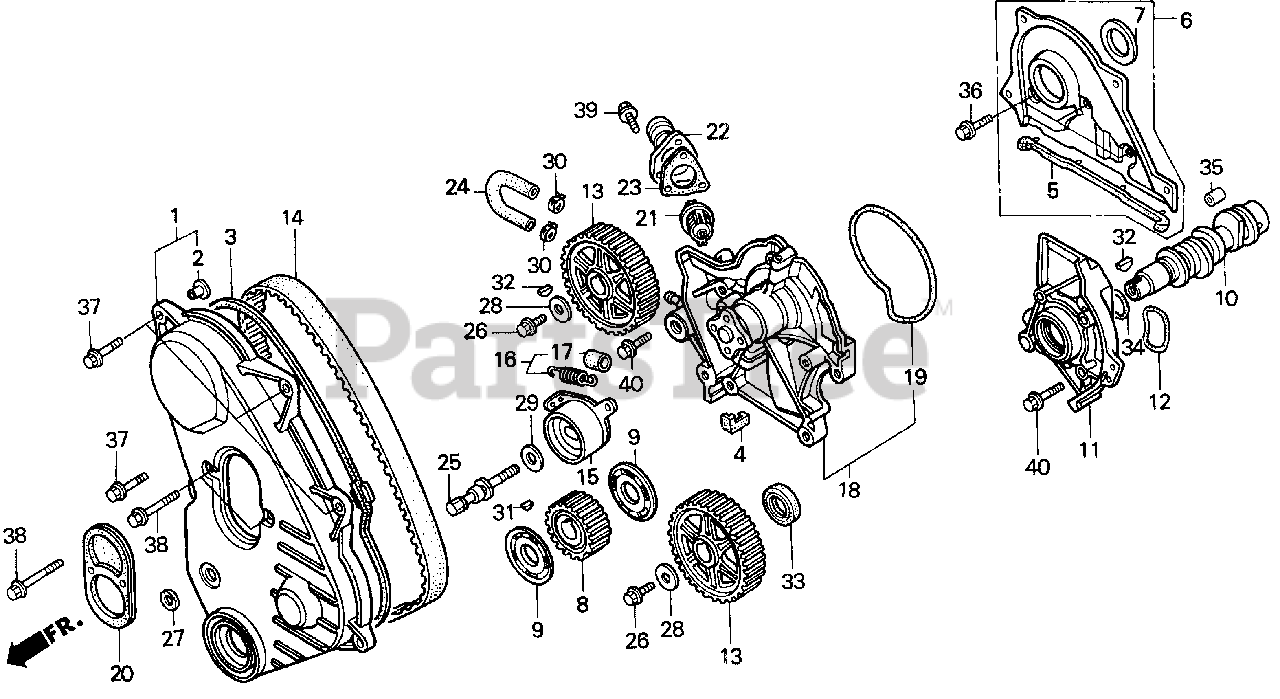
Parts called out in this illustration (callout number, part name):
1	COVER A, TIMING BELT
2	COLLAR, TIMING BELT COVER (LOWER)
3	RUBBER A, SEAL
4	RUBBER, R. BACK SEAL
5	RUBBER C, SEAL
6	COVER, RR. TIMING BELT
7	RUBBER, RR. COVER SEAL
8	PULLEY, TIMING BELT DRIVE
9	PLATE, TIMING BELT GUIDE
10	CAMSHAFT, FUEL
11	COVER, FUEL CAM
12	GASKET, FUEL CAM COVER
13	PULLEY, TIMING BELT DRIVEN
14	BELT, TIMING
15	TENSIONER, TIMING BELT
16	SPRING, TIMING BELT ADJUSTING
17	BOOT, SPRING
18	WATER PUMP
19	O-RING, WATER PUMP
20	RUBBER, WATER PUMP SEAL
21	THERMOSTAT
22	COVER, THERMOSTAT
23	GASKET, THERMOSTAT COVER (NON-ASBESTOS)
24	HOSE, WATER BYPASS
25	BOLT, TIMING BELT ADJUSTER
26	BOLT, FLANGE (8X22)
26	BOLT-WASHER (8X22)
27	RUBBER, TIMING BELT ADJUSTER
28	WASHER, SPECIAL (28X8.5X4.0)
29	WASHER (10.3X25)
30	CLAMP, CANISTER HOSE
31	KEY (4.5X11.0)
32	KEY (25.4X13)
33	OIL SEAL (29X45X8)
34	O-RING (64X2.3)
35	PIN, DOWEL (10X12)
36	BOLT, FLANGE (6X12)
37	BOLT, FLANGE (6X16)
38	BOLT, FLANGE (6X20)
39	BOLT, FLANGE (6X25)
40	BOLT, FLANGE (8X35)
